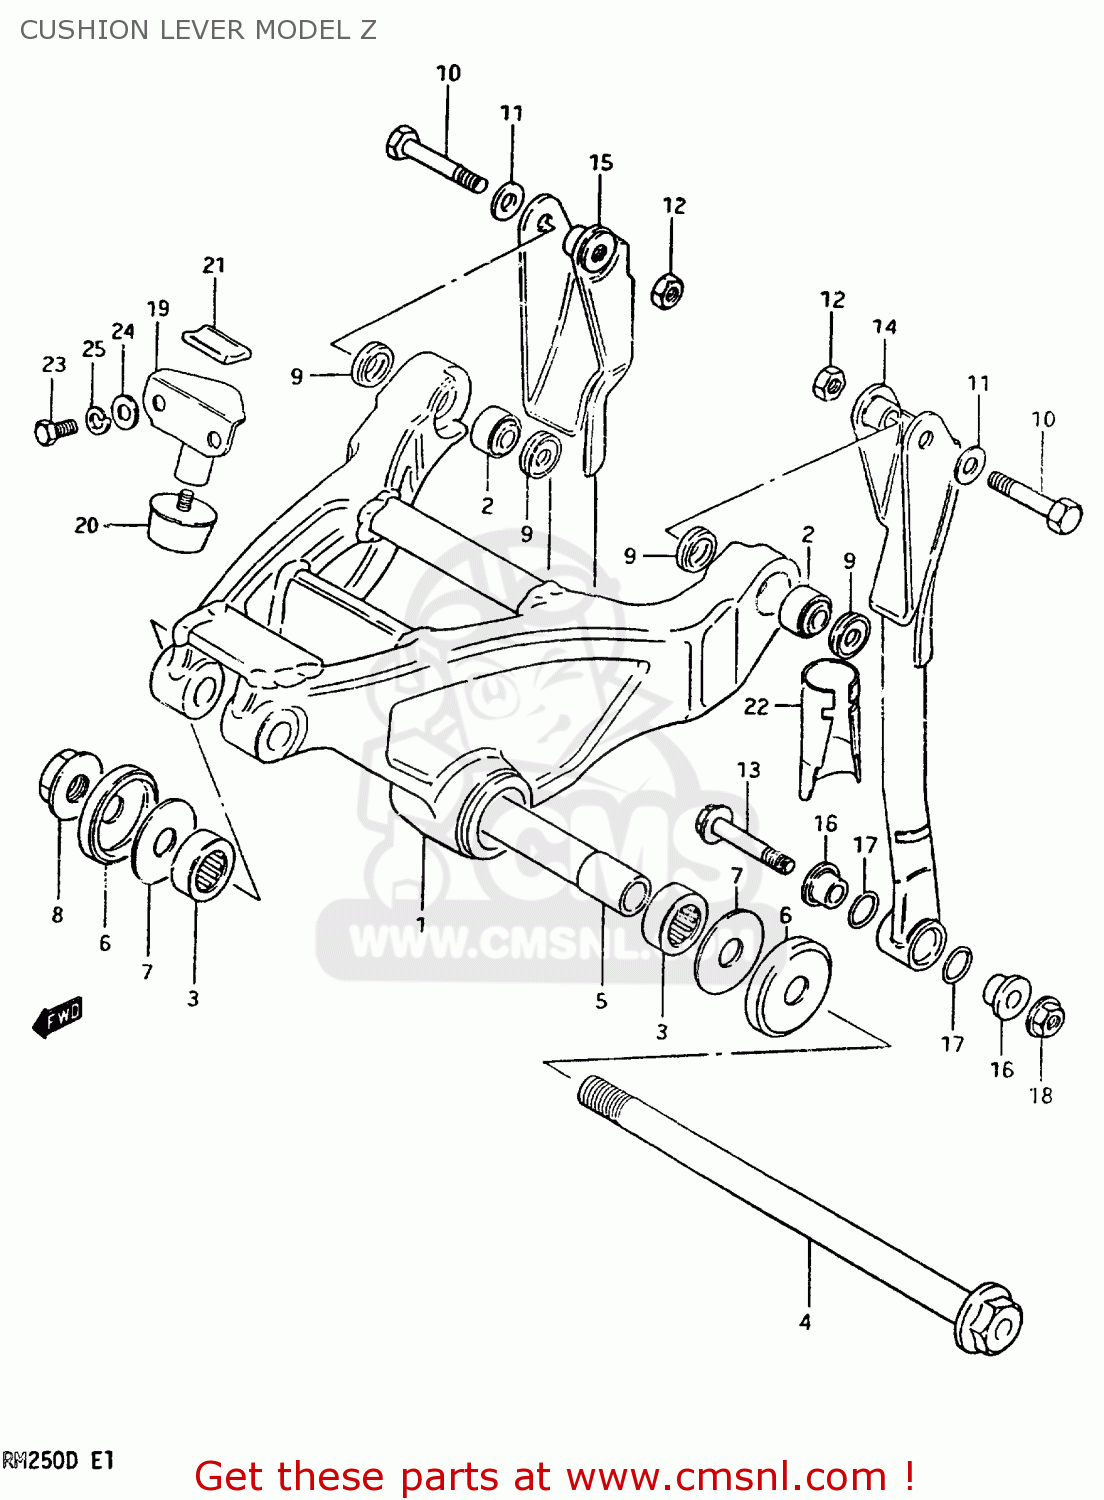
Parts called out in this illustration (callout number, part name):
1	LEVER SET,REAR CUSHION
2	BEARING(8X18X11)
3	BEARING(17X26X20)
4	SHAFT,REAR CUSHION LEVER
5	SPACER,REAR CUSHION LEVER
6	DUST SEAL
7	WASHER(12X35X2)
8	NUT 12MM
9	DUST SEAL,RR CUSHION LOD UPR.
10	BOLT 8X38
11	WASHER
12	NUT
13	BOLT 8X45
14	ROD,REAR CUSHION LEVER,LEFT
15	ROD,REAR CUSHION LEVER,RIGHT
16	SPACER,RR CUSHION ROD LWR
17	DUST SEAL,RR CUSHION LOD LWR
18	NUT
19	STOPPER,TENSION
20	RUBBER,TENSION STOPPER
21	SUPPORT RUB TENS
22	PROTECTOR,REAR CUSHION R
23	BOLT
24	WASHER
25	WASHER,LOCK
